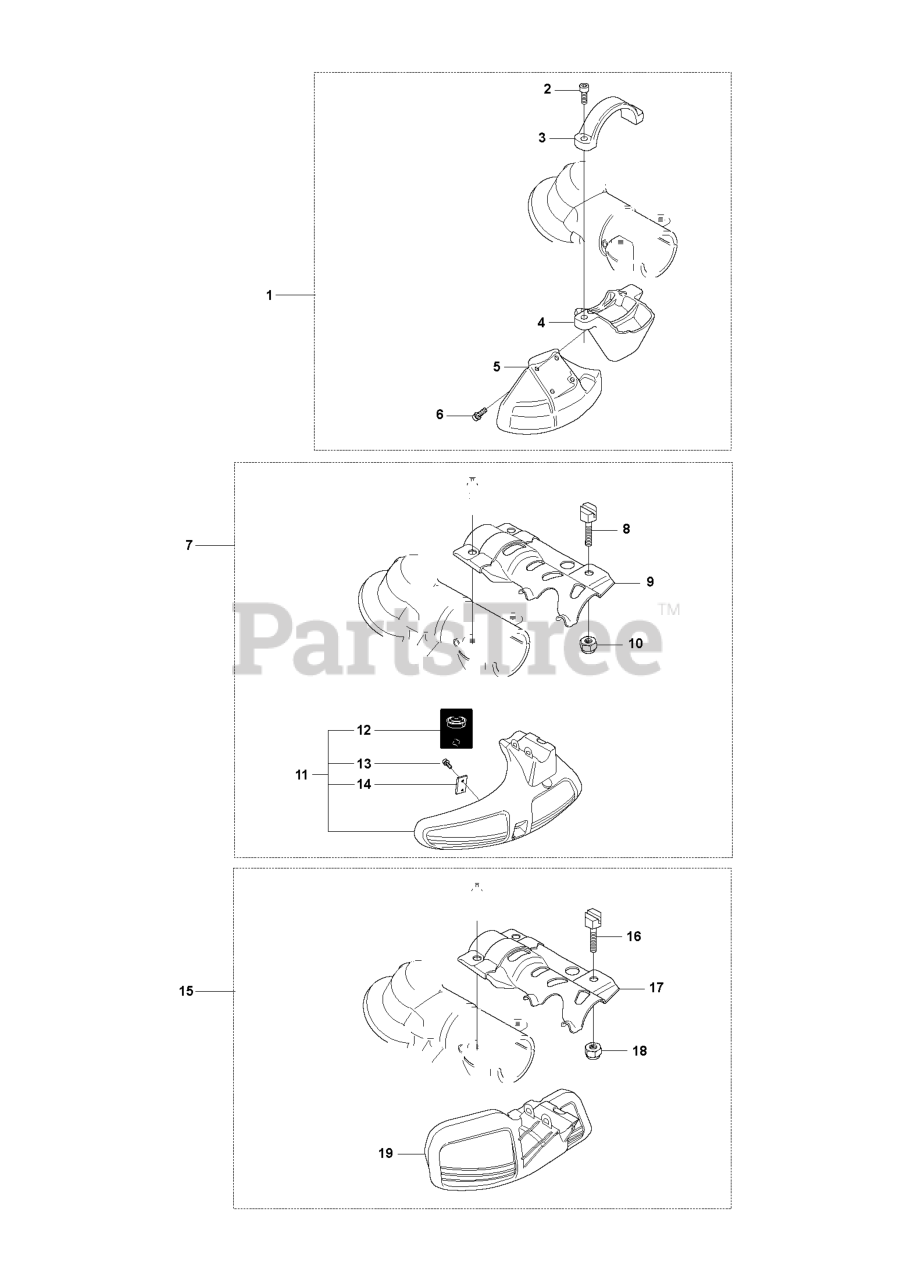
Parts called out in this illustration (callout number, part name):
1	TRIMMER GUARD ASSY
4	ADAPTER
5	RP BLADE GUARD
6	SCREW
7	SPLASH GUARD KIT
8	SCREW
9	PLATE
10	LOCKNUT M6
12	DECAL
13	SCREW
14	BLADE
15	TRIMMER GUARD ASSY
16	SCREW
17	PLATE
18	LOCKNUT M6
19	PROTCTOR
